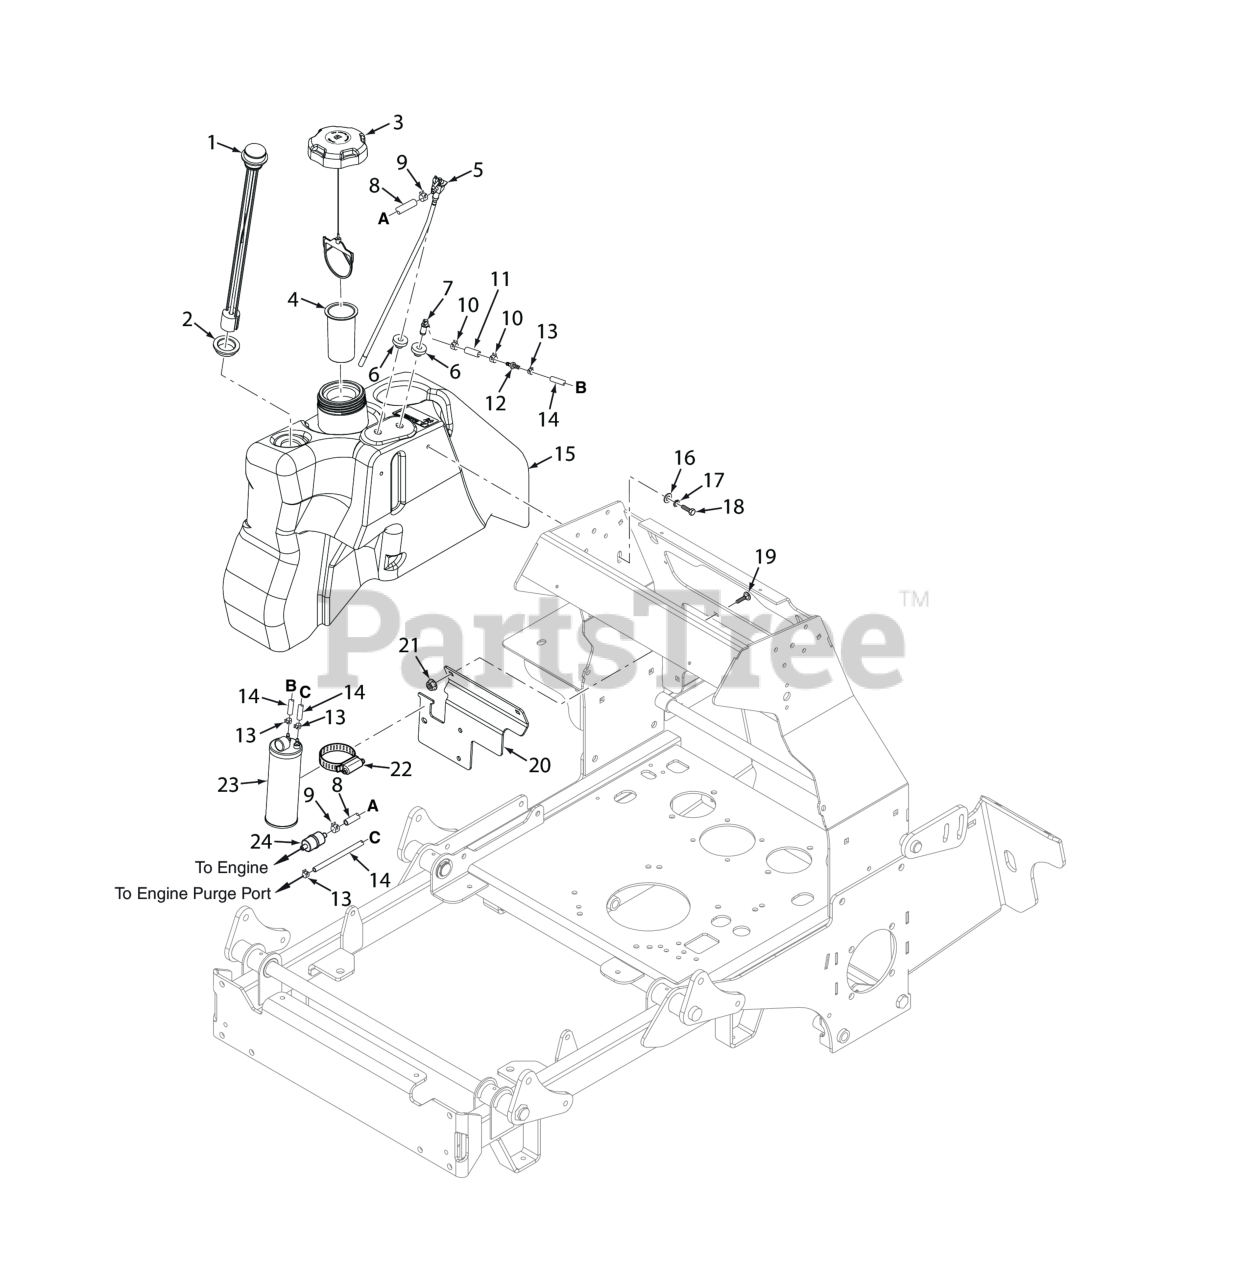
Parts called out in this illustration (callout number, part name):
1	Fuel Gauge Assy., 16-1/2"
2	Grommet, Fuel Gauge
3	Fuel Cap w/ Tether (E.P.A.)
3	Fuel Cap, Tethered - CA models only
4	Tube, Fuel Tank Insert - 4"
5	Valve, Fuel Shut Off
6	Bushing, 0.56" Dia. Viton
7	Remote Vent
8	Fuel Hose, 1/4" I.D. Non-Perm (791DFI Fuel Return) - Order by Inch
9	Clamp, Fuel Hose 1/4" Hose I.D.
10	CLAMP, FUEL HOSE(KAWASAKI ONLY)
11	Hose, 1/4" Vapor Recovery (order by inch)
12	Mender, 1/4 x 3/16 w/0.02 Hole
13	Clamp, Vapor Recovery Hose 3/16"
14	Hose, Vapor Recovery 3/16" (order by inch)
15	Fuel Tank Assy., SVRII-36 (Incl. #1,2,5,6,7)
16	Flatwasher, 5/16-.375 x .875 x .083 (35BV & 37BV-EFI)
17	Lockwasher, 5/16 (.317 x .586 x .078) Helical Spring
18	BOLT, SERRATED FLANGE HEX HEAD 5/16-18 X 3/4"
19	Bolt, 5/16-18 x .75 RHSN Carriage
20	Bracket, Hydro Tank Mounting
21	Nut, Serrated Flange 5/16-18 (Right Front Engine Mounting, Briggs and Kohler Only)
22	Clamp, 3-1/2" Max. Dia.
23	Carbon Canister - SVR-52V / SVR-61V
24	Dust Filter, Carbon Canister
